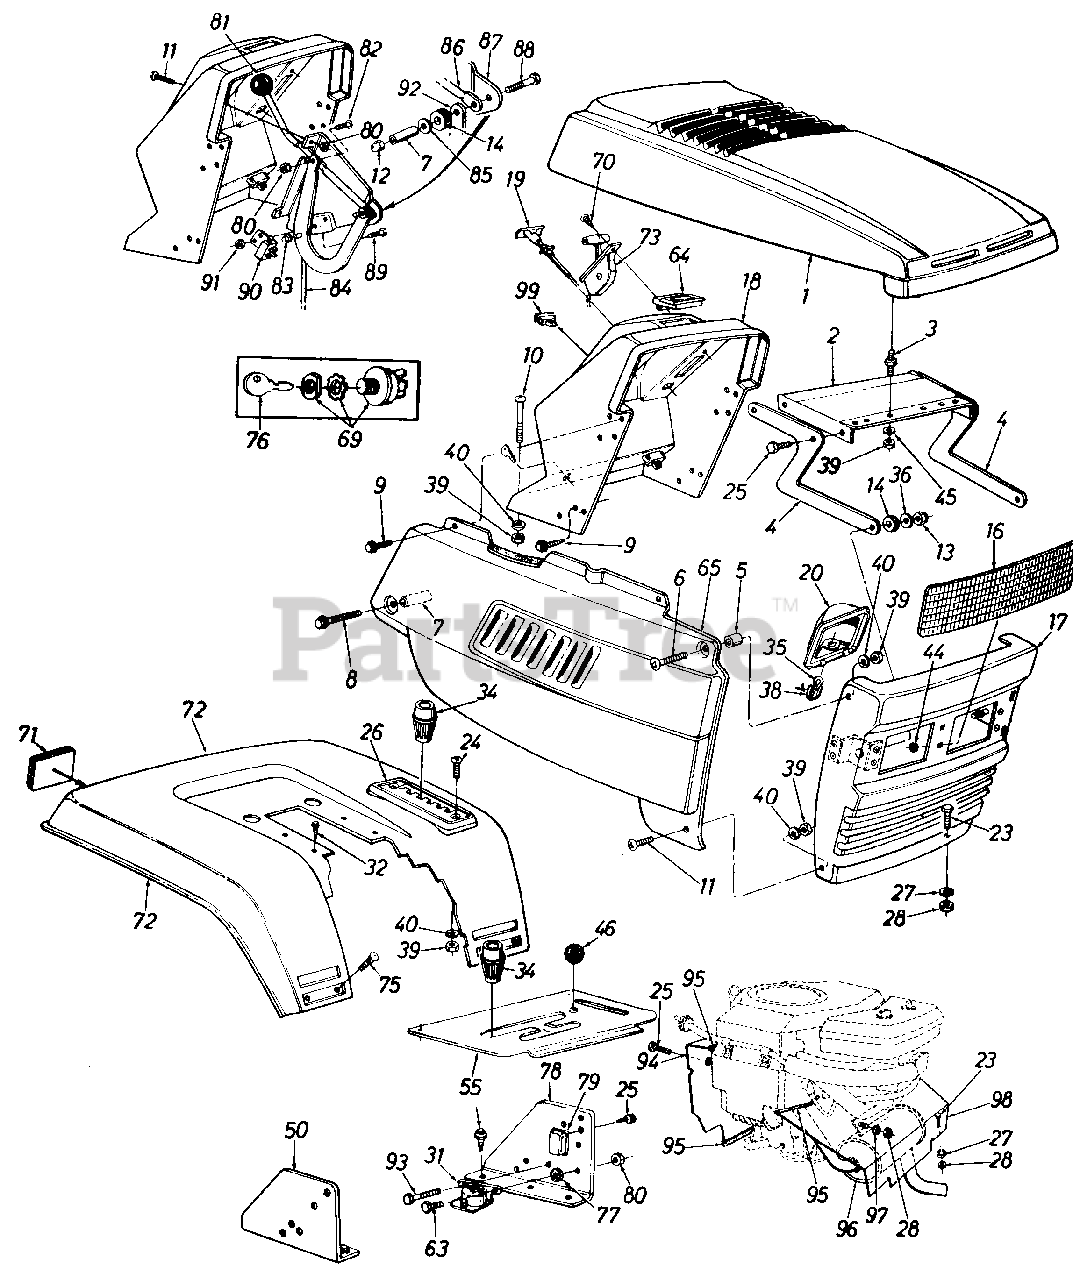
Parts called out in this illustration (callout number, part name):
2	Hood Plate
3	Double Ended Stud 1/4-20 Thd.
4	Hood Hinge
5	Spacer .34" I.D. x .437"
6	Truss Hd. Mach. Scr. 1/4-20 Thd.
7	Spacer .26" I.D. x .375"
8	Hex Wash. TT-Tap Scr. 1/4-20 x 1.75" Lg.
9	Hex T-Tap Scr. 1/4-20 x .75" Lg.
10	Truss Mach. Scr. 1/4-20 x 1.75" Lg.
11	Truss Mach. Scr. 1/4-20 x .5" Lg.
12	Hex Ins. L-Nut 1/4-20 Thd.
13	Hex L-Nut 5/16-18 Thd.
14	Rubber Washer
16	Headlight Lens
19	Choke Control
20	Headlight Housing
23	Hex Bolt 5/16-18 x .75" Lg.
24	Truss Mach. Scr. 1/4-20 x .62"Lg.
25	Hex Wash. Hd. Scr. 1/4" x .5" Lg.
26	7-Speed Index Brkt.
27	L-Wash. 5/16" I.D.
28	Hex Nut 5/16-18 Thd.
31	Solenoid
32	Hex Hd. Rolling Scr. 5/16-24 x .75" Lg.
34	Shift Knob
35	Lamp
36	Bell-Wash. .34" I.D. x .87"
38	Socket
39	Hex Nut 1/4-20 Thd.
40	L-Wash. 1/4" I.D.
44	Speed Nut 5/16" I.D.
45	Bell-Wash. .265" I.D. x .75" O.D.
46	Ball Knob Brake
50	Dash Support Brkt. R.H.
55	Transmission Cover Ass'y.
63	Hex Bolt 1/4-20 x .5" Lg.
64	Ammeter
70	Truss Mach. AB-Tap Scr. #10 x .5" Lg.
71	Reflector
75	Carriage Bolt 1/4-20 x .5" Lg.
76	Key
77	Ext. L-Wash. 1/4" I.D.
78	Dash Support Brkt. L.H.
79	Circuit Breaker
80	Hex Sems Nut 1/4-20 Thd.
81	Ball Knob
82	Hex Bolt 1/4-20 x .62" Lg.
83	Push Nut
84	PTO Rod
85	Fl-Wash. .281" I.D. x .73"
86	PTO Lever
87	Deck Clutch Control Brkt.
88	Hex Bolt 1/4-20 x 2.5" Lg.
89	Truss Mach. Scr. #10-24 x .5"Lg.
90	Safety Switch
91	Hex Nut #10-24 Thd.
92	PTO Bracket
93	Self Clinching Stud 1/4-20 x .5" Lg.
94	Engine Baffle
95	Trim Strip 10" Lg.
96	Muffler
97	Spec. L-Wash. 5/16" I.D.
98	Front Heat Shield
99	Light Switch
